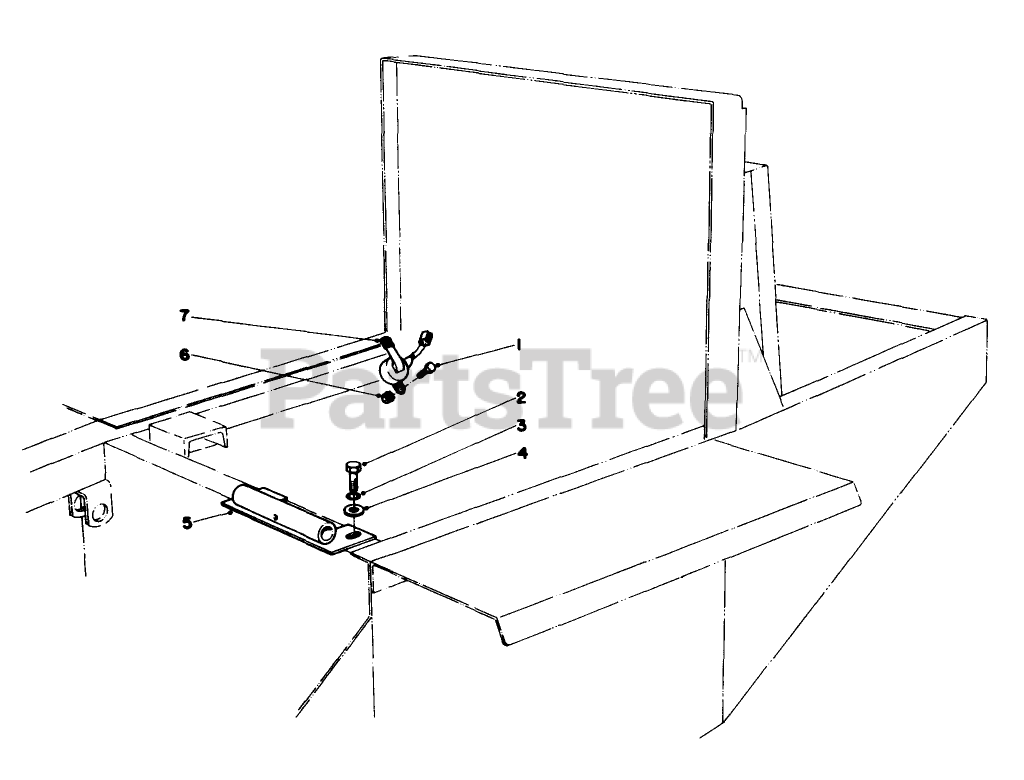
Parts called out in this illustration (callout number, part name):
1	SCREW-HH
2	SCREW-HH
3	WASHER-LOCK
4	WASHER-PLAIN
5	Pivot-Seat
6	NUT-LOCK, NI
7	SWITCH ARM
